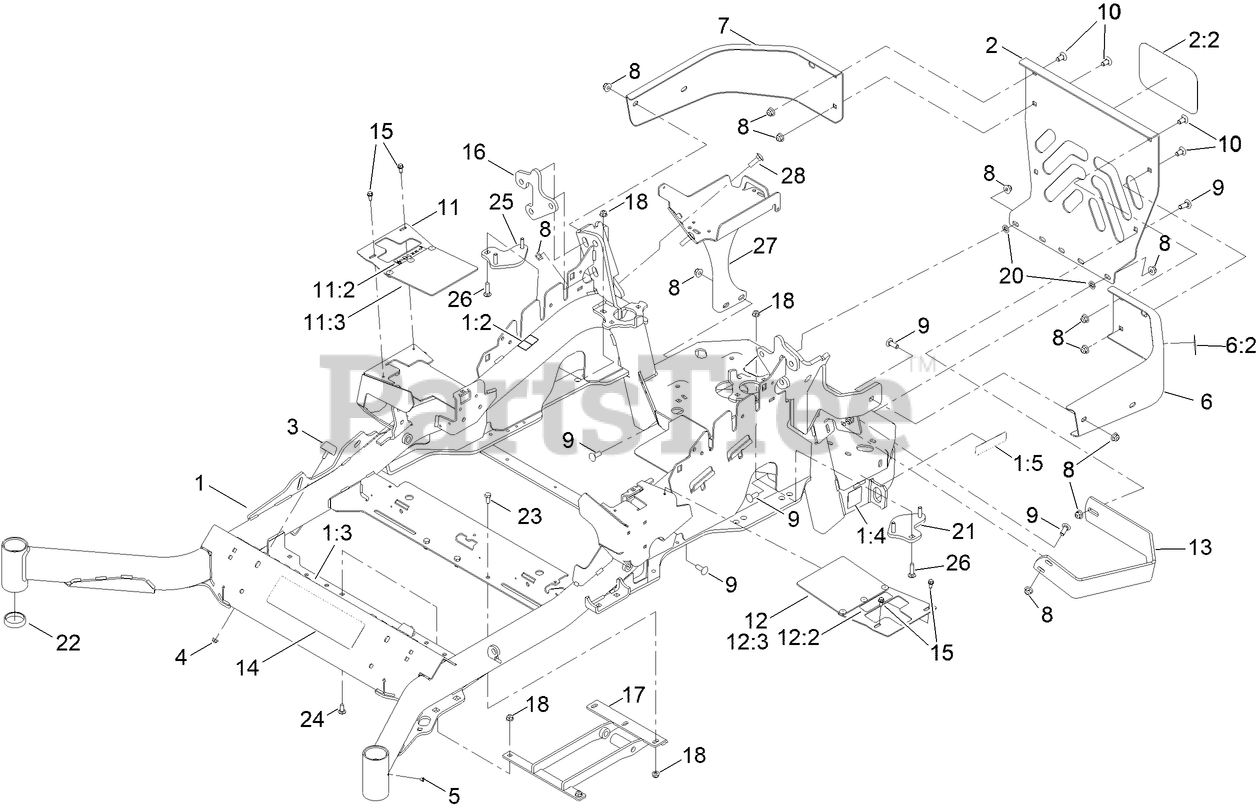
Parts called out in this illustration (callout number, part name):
1	MAINFRAME SERVICE ASM - 72
1:2	DECAL-WARNING
1:3	DECAL-DANGER
1:4	DECAL-HAZARD, PINCHED FINGER
1:5	DECAL-ARRESTOR, SPARK
2	REAR GUARD ASM
2:2	DECAL
3	BUMPER
4	NUT-HF
6	LH BUMPER ASM
6:2	DECAL-WARNING
7	BUMPER-RH
8	NUT-HF, NI
9	SCREW-CARR
10	SCREW-CARR
11	RH MOTION CONTROL COVER ASM
11:2	DECAL-CONTROL, MOTION
11:3	FLAP-RUBBER
12	LH MOTION CONTROL COVER ASM
12:2	DECAL-CONTROL, MOTION
12:3	FLAP-RUBBER
13	GUARD-MUFFLER
14	DECAL-CONSOLE
15	SCREW-HWH
16	PLATE-MOUNT, SHOCK
17	MOUNT-LOWER
18	NUT-HF, NI
20	NUT-PUSH
21	LH PLATE ASM (W/STUDS)
22	CUP-BEARING
23	SCREW-HH
24	SCREW-CARR
25	RH PLATE ASM (W/STUDS)
26	SCREW-CARR
27	BATTERY MOUNT ASM
28	BOLT-CARR
